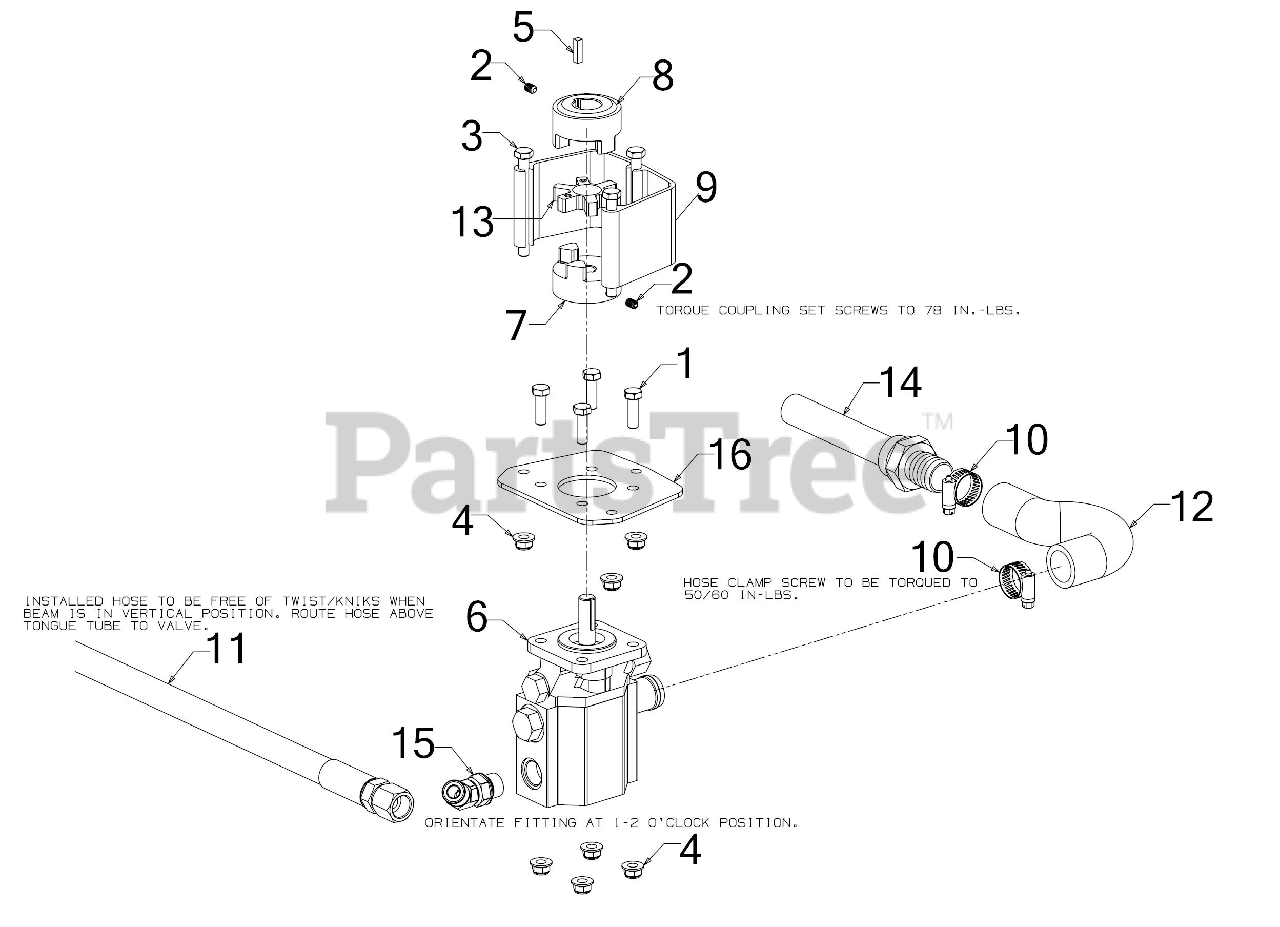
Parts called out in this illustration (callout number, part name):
1	SCREW 5/16-18 x 1.0 GR5
2	SCREW 1/4-20 x .38
3	SCREW 5/16-18 x 3.25 GR5
4	FLANGE LOCK NUT 5/16-18
5	SQUARE KEY 3/16 x .7
6	LOGSPLITTER GEAR PUMP 11GPM
7	LOGSPLITTER COUPLING .500
8	LOGSPLITTER COUPLING .875
9	COUPLING SHIELD
10	HOSE CLAMP-5/8
11	48" HYDRAULIC HOSE
12	INLET HOSE
13	SPIDER COUPLING BUSHING
14	INLET FILTER
15	HYDRAULIC FITTING
16	SUPPORT BRACKET
